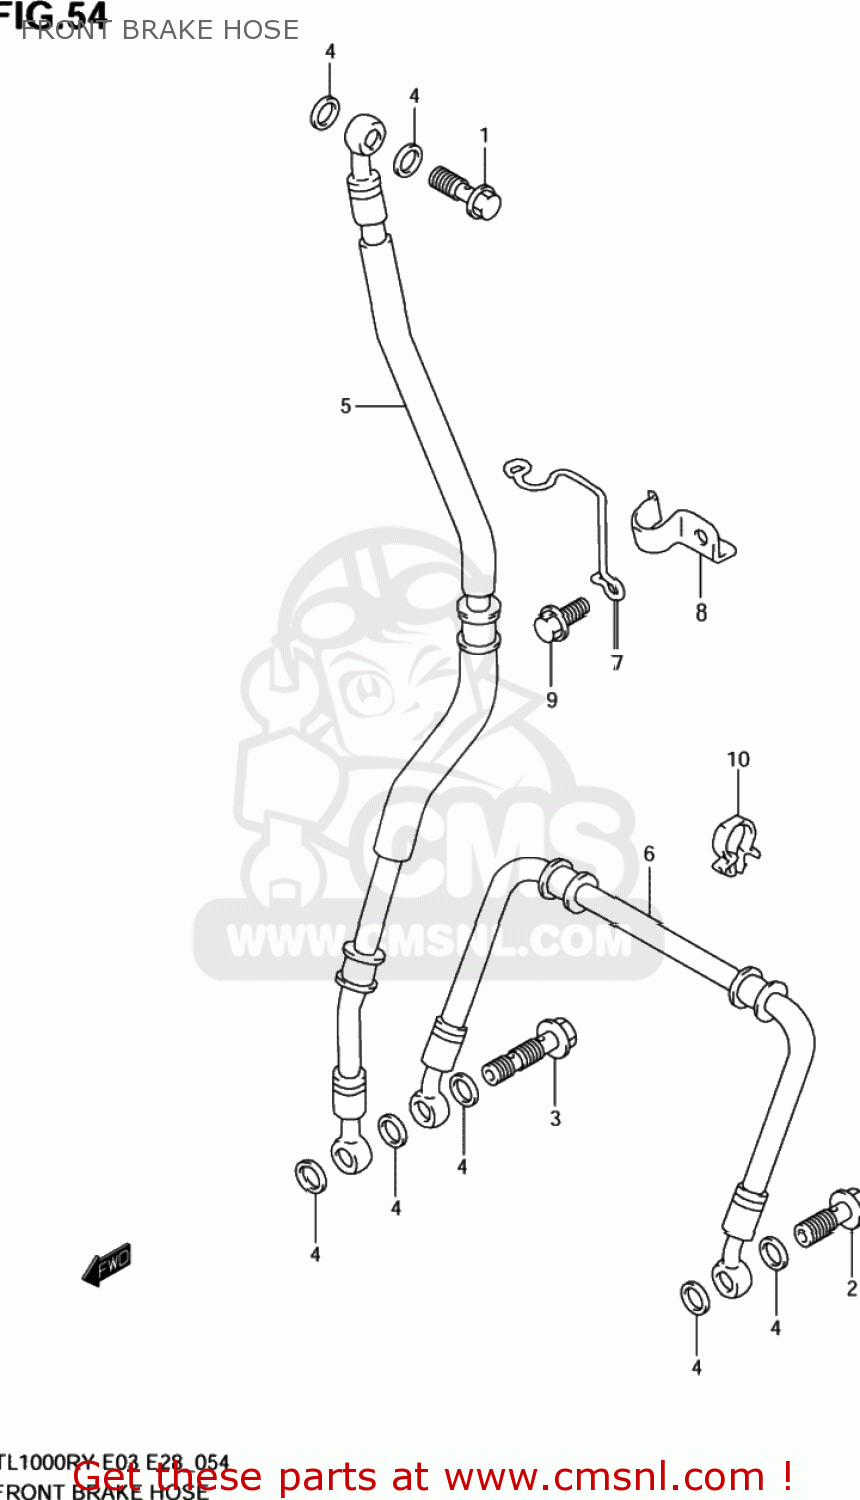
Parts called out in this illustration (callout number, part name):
1	BOLT UNION
2	BOLT UNION
3	BOLT UNION
4	WASHER(10X15X1.5)
5	HOSE,FR BRAKE NO.1
6	HOSE,FR BRAKE NO.2
7	GUIDE,FRONT BRAKE HOSE
8	CLAMP,FR BRAKE HOSE UPR
9	BOLT
10	CLAMP
